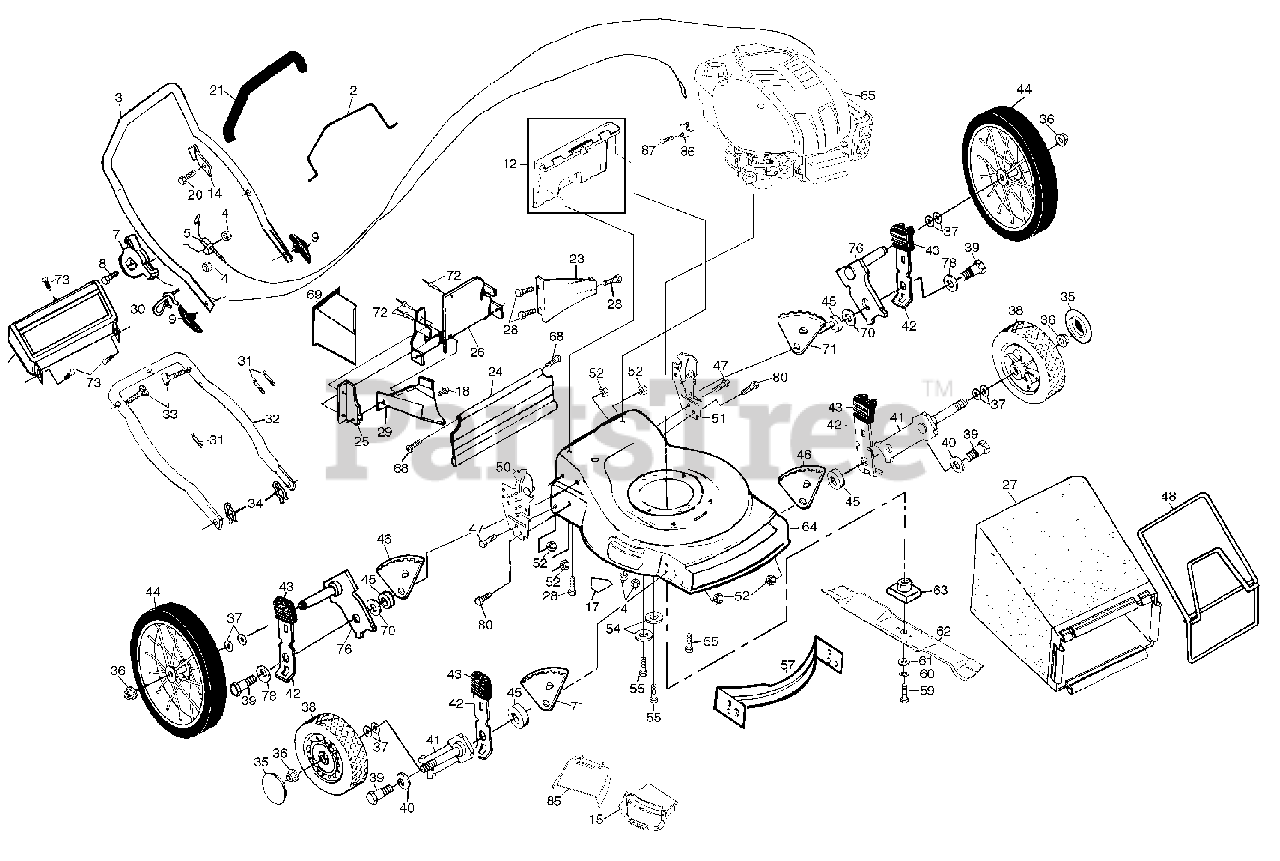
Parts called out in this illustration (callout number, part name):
2	Control Bar
3	Upper Handle
4	Locknut
5	Engine Zone Control Cable
7	Throttle Control
8	Hex Washer Head Screw 1/4-20 x 2-1/8
9	Handle Knob
12	Rear Door Kit
14	Upstop Bracket
15	Combi-Cut Mulcher
17	Danger Decal
20	Hex Washer Head Screw #10-24
21	Handle Grip
22	Trim Plate
23	Rear Baffle
24	Rear Skirt
25	Side Baffle
26	Back Plate
27	Grass Bag
28	Screw Hex Head 1/4-20 x 1/2
29	Discharge Baffle
30	Rope Guide
31	Wire Ties
32	Lower Handle
33	Handle Bolt
34	Hairpin Cotter
36	Flanged Locknut
37	Wave Washer
38	Wheel & Tire Assembly (Front)
39	Shoulder Bolt
40	Belleville Washer
41	Axle Arm
42	Selector Spring
43	Selector Knob
44	Wheel & Tire Assembly (Rear)
45	Spacer
46	Wheel Adjusting Bracket R. R.
47	Self-tapping Screw 5/16-18 x 3/4
48	Catcher Frame
50	Handle Bracket (Right)
51	Handle Bracket (Left)
52	Locknut 3/8-16
55	Hex Head Thread Rolling Screw 3/8-16 x 1
57	Front Baffle
59	Hex Head Machine Screw 3/8-24 x 1-3/8 Gr. 8
60	Helical Lock Washer
61	Hardened Washer
63	Blade Adapter
64	Lawn Mower Housing Kit
68	Hinge Screw
69	Mulcher Plug
70	Flat Washer
71	Wheel Adjusting Bracket L. R.
73	Push-in Fastener
76	Axle Arm Assembly
78	Spacer
85	Clip on Guard
86	Cable Clamp
